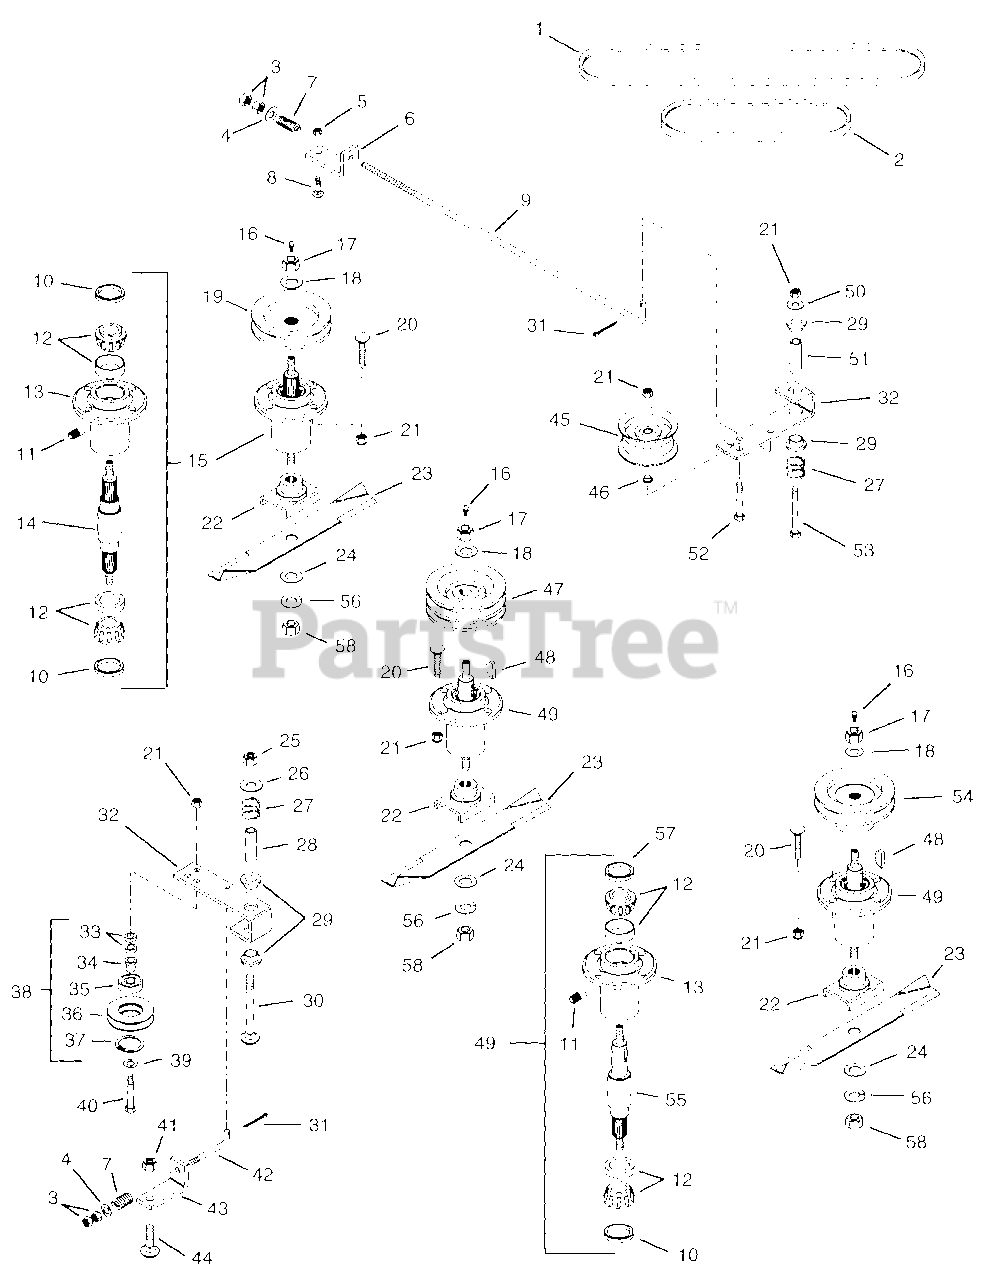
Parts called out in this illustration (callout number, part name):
1	V-Belt, A-Section 42.15 x .516/.031
2	V-Belt, A-Section 18.05 x .495
3	Nut-Hex.375-16 Grade 2
4	Washer-Flat-Steel .406 x .812 x .065
5	Nut-Locking-Nylon .312-18 w/Insr Grade 2
6	Bracket, Belt Tensioner
7	Spring-Compression .125 x .781 x 1.00 338 Ibs/in
8	Bolt, Round Head Square Neck .31-18 x 1.0
9	Rod, Idler Left Hand
10	Seal 1.987 x 1.375 x .313 Cross Recessed
11	Relief Fitting, Grease
12	Assembly, Bearing Cup and Cone
13	Bearing Housing
14	Shaft, Spindle
15	Service Kit, Spindle Assembly
16	Fitting, Lube 1/8
17	Nut-Locking-Nylon .625-11 Grade 2
18	Washer-Flat-Steel .687 x 1.312 x .135
19	Sheave
20	Bolt, Round Head Square Neck .31-16 x 1.375
21	Nut-Locking-Nylon .375-16 w/Insr Grade 2
22	Weldment, Blade Cradle
23	Blade, 50" Mower
24	Washer-Flat-Steel .656 x 1.312 x .095
25	Nut-Locking .50-13 Hex Type Needle
26	Washer-Flat-Steel .531 x 1.250 x .100
27	Spring-Compression .085 x .80 x 1.00
28	Spacer, .560 x .750 x 2.437 Steel
29	Bushing-Flange .762 x 1.0 x .580 x 1.48 Nylon
30	Bolt, Round Head Square Neck .50-13 x 3.50
31	Pin, Cotter .09 x .75
32	Arm, Idler Pivot
33	Bushing .406 x .750 .188
34	Bushing-Flange .786 x 1.0 x .79
35	Bearing-Ball 1.85 x .787 x .55
36	Sheave, Idler
37	Ring-Retaining-internal 2.054 x .062
38	Assembly, Idler Sheave
39	Washer-Flat-Steel .375 x 1.125 x .065
40	Bolt-Hex .38-16 x 2.00 Grade 5
41	Nut-Locking-Nylon .50-13 Grade 5
42	Rod, Idler
43	Bracket, Tensioner
44	Bolt, Round Head Square Neck .31-18 x 1.50
45	Bracket, Belt Tensioner
46	Bushing-Flange .406 x .88 x .270 x .140
47	Sheave
48	Key, Woodruff .25 x 1 Hard #15
49	Service Kit, Spindle Assembly
50	Washer-Flat-Steel .438 x 1.000 x .083
51	Bushing, Steel .437 x .750 x 2.44
52	Bolt-Hex .28-16 x 2.25 Grade 5
53	Hot-Hex .38-16 x 3.25 Grade 5
54	Sheave
55	Shaft, Spindle
56	Washer-Lock .625 x .156
57	Seal 1.987 x 1.500 x .313
58	Nut-Hex .625-11 Grade 2
